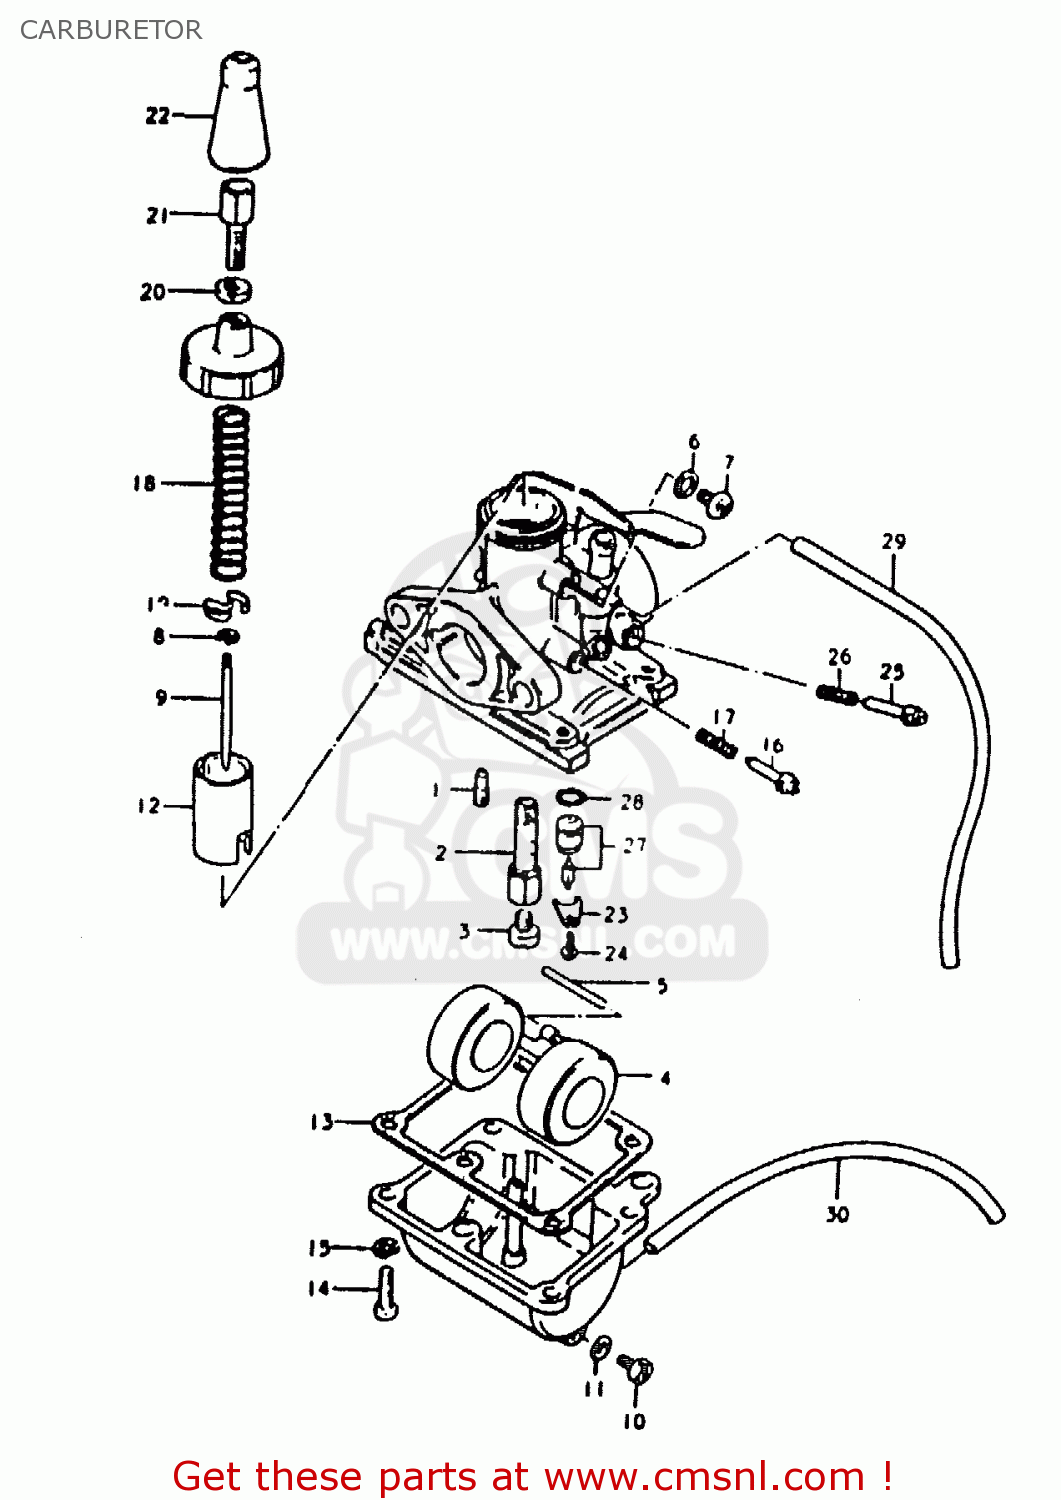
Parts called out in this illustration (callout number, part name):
1	JET,PILOT
2	JET, NEEDLE (E-7)
3	JET,MAIN(70)
4	FLOAT
5	PIN,FLOAT
6	RING
7	SCREW
8	CLIP,NEEDLE
9	NEEDLE,JET
10	PLUG
11	GASKET,DRAIN,PLUG (NAS)
12	VALVE,THROTTLE(CA:2.0)
13	GASKET,FLOAT CHAMBER (NAS)
14	SCREW
15	LOCK WASHER
16	SCREW,THROTTLE STOP
17	SPRING
18	SPRING,THROTTLE VALVE RETURN
19	PLATE,THROTTLE VALVE
20	NUT
21	ADJUSTER,CABLE
22	BOOT
23	PLATE,NEEDLE VALVE FITING
24	SCREW
25	SCREW,AIR
26	SPRING
27	VALVE ASSY,NEEDLE
28	O RING
29	HOSE
30	HOSE
